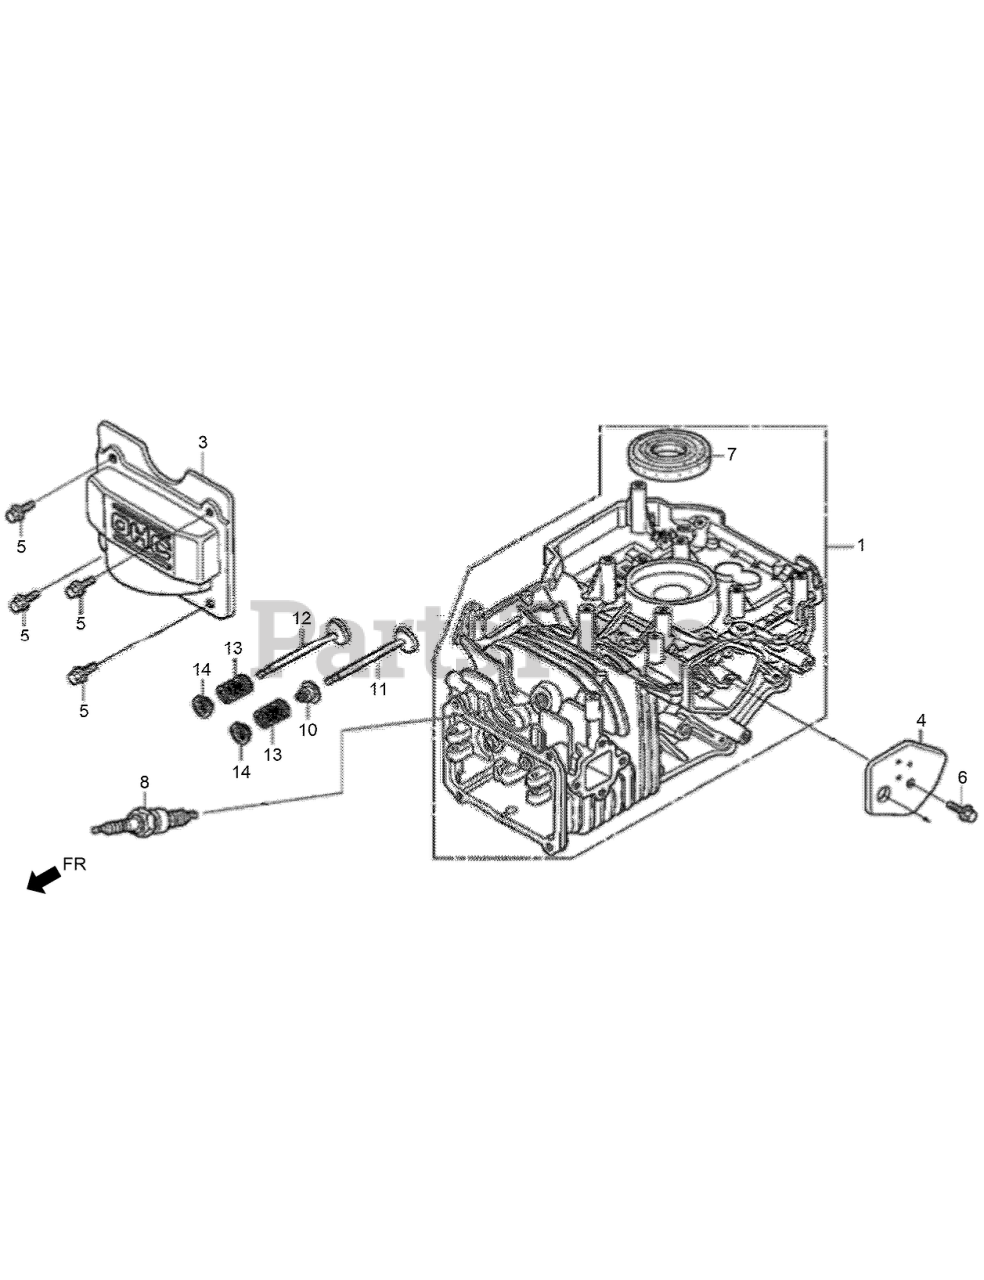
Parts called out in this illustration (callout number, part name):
1	BARREL ASM-CYLINDER
3	COVER-HEAD
4	BREATHER COVER ASM
5	BOLT-FLANGE-6X12
6	BOLT-FLANGE-6X14
7	OIL SEAL-25.4X62X6
8	SPARKPLUG
10	SEAL-VALVE STEM
11	VALVE-INTAKE
12	VALVE-EXHAUST
13	SPRING-VALVE
14	RETAINER-INTAKE VALVE SPRING
